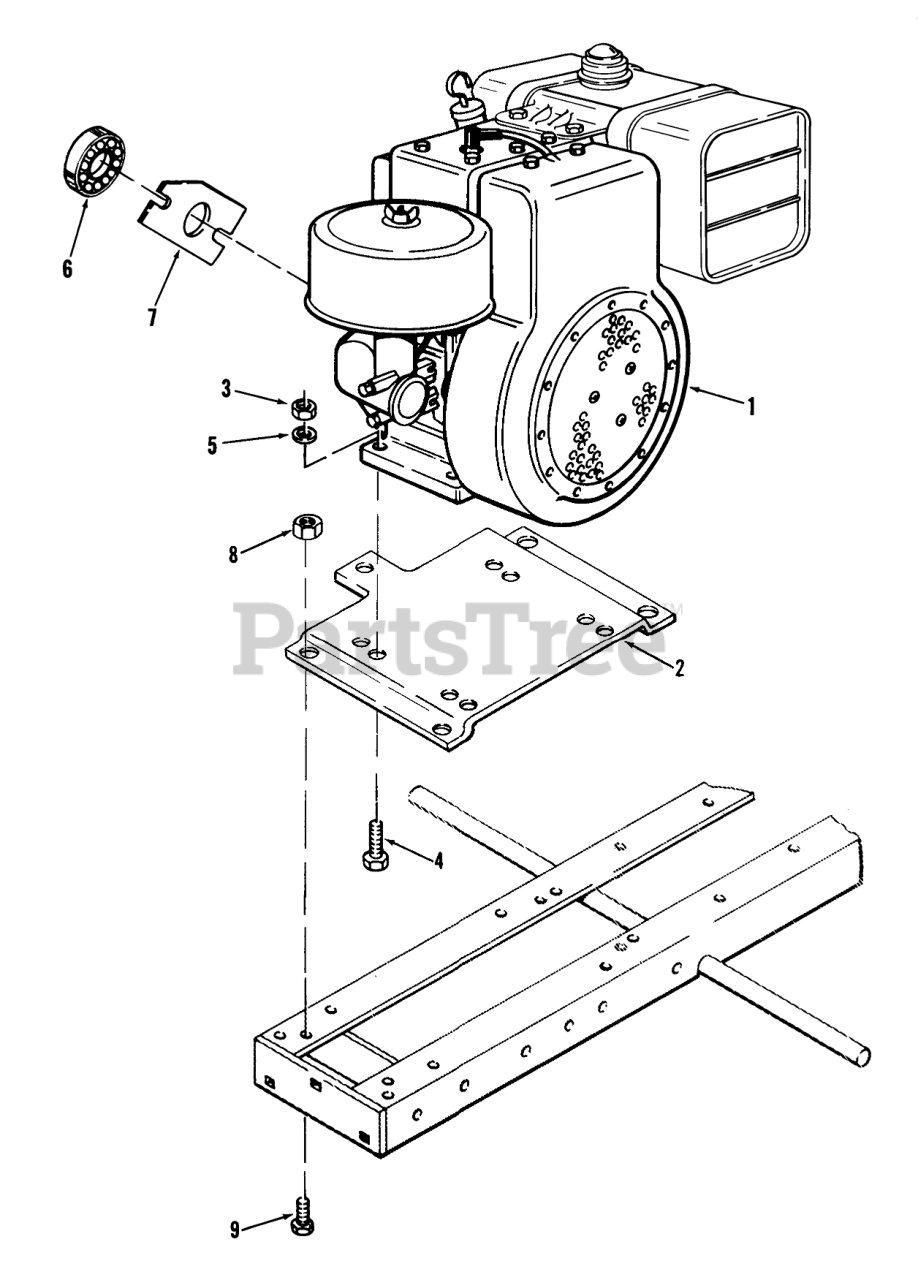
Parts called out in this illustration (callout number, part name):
1	Engine-11 HP Briggs & Stratton 252417 Type 0245-01
2	Engine Cradle
3	Nut
4	HHCS
5	Lockwasher
6	BEARING-BALL
7	PLATE-THRUST B
8	NUT
9	BOLT
